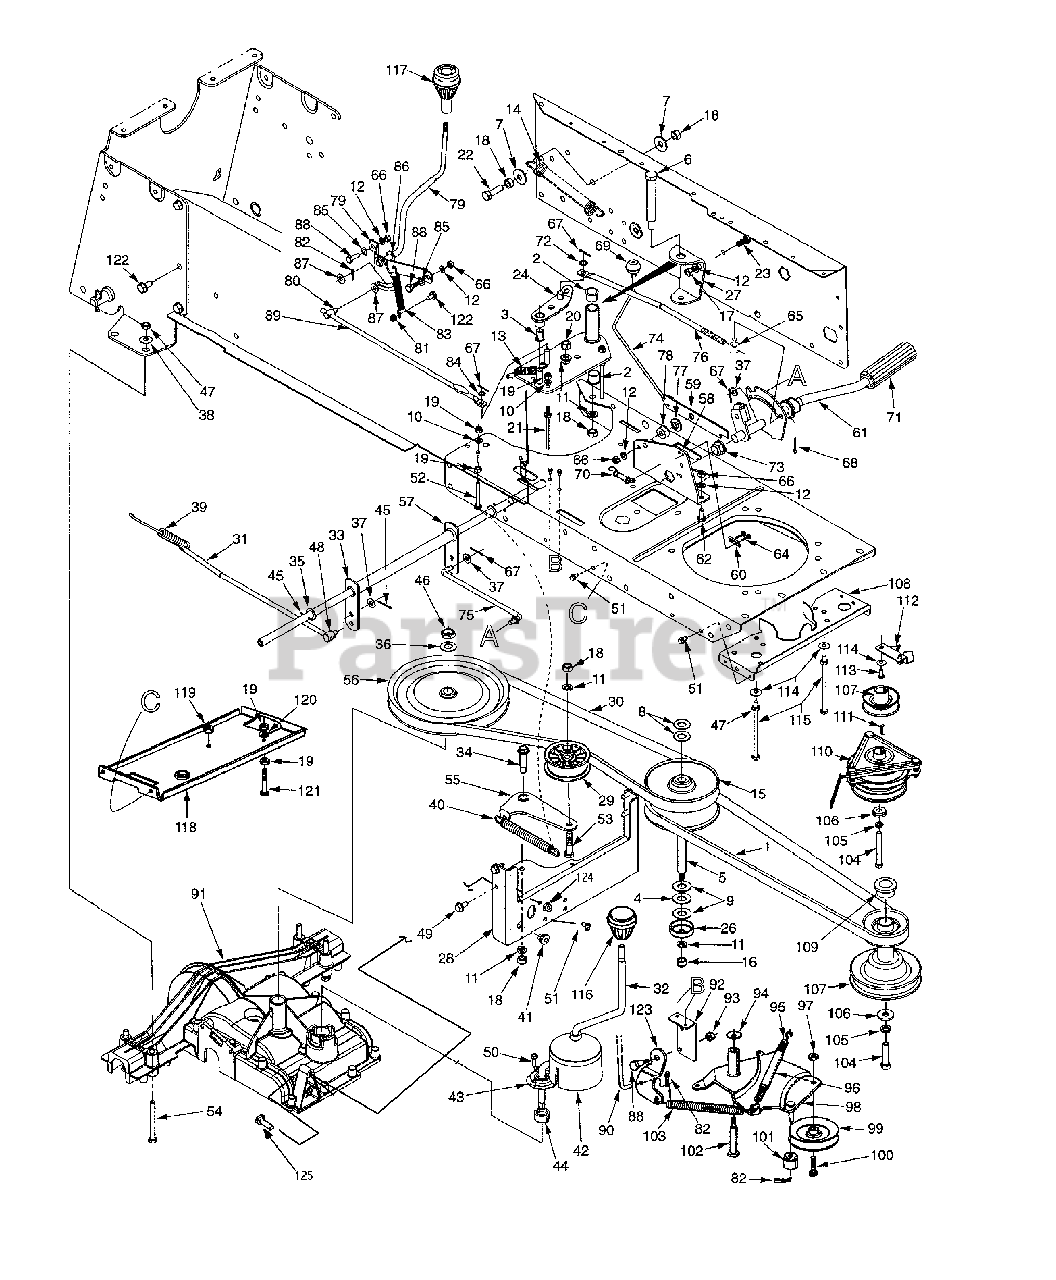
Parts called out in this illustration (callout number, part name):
1	"V"-Belt
2	Flange Brg.
3	Flange Nyliner Brg.
4	Thrust Brg.
5	Shaft
6	Shld. Bolt 3/8-24 Thd.
7	Bell-Wash. .396" I.D. x 1.14" O.D.
8	Fl-Wash. .56" I.D. x 1.12" O.D.
9	Fl-Wash. .5" I.D. x 1" O.D.
10	L-Wash. 1/4" I.D.
11	L-Wash. 3/8" I.D.
12	L-Wash. 5/16" I.D.
13	Ext. Spring 2.54" Lg.
14	Ext. Spring 6.96" Lg.
15	Variable Speed Pulley
16	Hex L-Nut 3/8-24 Thd.
17	Hex Nut 5/16-24 Thd. (Gr. 5)
18	Hex Nut 3/8-16 Thd. (Gr. 5)
19	Hex Nut 1/4-20 Thd. (Gr. 5)
20	Hex Nut 3/8-24 Thd.
21	Belt Keeper
22	Hex Bolt 3/8-16 x 1.25" Lg.
23	Hex Bolt 5/16-24 x .75" Lg. (Gr. 5)
27	Support Brkt.
30	"V"-Belt
31	Brake Rod
32	Shift Lever
33	Flange Nyliner Brg.
34	Shld. Bolt 3/8-16 Thd.
35	Fl-Wash. .5" I.D. x .875" O.D.
36	Bell-Wash. .567" I.D. x 1.125" O.D.
37	Fl-Wash. 5/16" I.D.
38	Bell-Wash. .345" I.D. x .88" O.D.
39	Ext. Spring 7.3" Lg.
40	Ext. Spring 6.12" Lg.
41	Plastic Bushing
42	Boot Shifter
43	Shifter Snout
44	Shifter Insert
45	Cotter Pin 1" Lg.
46	Hex Jam Nut 9/16-18 Thd.
47	Hex Nut 5/16-18 Thd. (Gr. 5)
48	Ferrule
49	Hex Wash. AB-Tap Scr. 5/16-18 Thd.
50	Hex Wash. TT-Tap. Scr. 1/4-20 x .75"
51	Hex Wash. Hd. TT-Tap Scr. 1/4-20 x .5"
52	Hex Bolt 1/4-20 x 2" Lg. (Gr. 5)
53	Hex Bolt 3/8-16 x 1.75" Lg. (Gr. 5)
54	Hex Bolt 5/16-18 x 3" Lg. (Gr. 5)
56	Trans. Pulley
64	Hex Hd. Tap Scr. #10-16 x .75" Lg.
65	Ferrule
66	Hex Nut 5/16-18 Thd.
67	Cotter Pin 1" Lg.
68	Cotter Pin 1/8" Dia. x 1" Lg.
69	Ball Knob
70	Ext. Spring 2.51" Lg.
71	Foot Pad
72	Fl-Wash. 3/8" I.D. x .62" O.D.
73	Hex Flange Bearing
74	Pedal Lock Rod
75	Brake Link Rod
76	Speed Control Link
77	Shld. Spacer
78	Spacer .34" I.D. x .87" O.D.
79	Speed Selector Lever Ass'y.
80	Ferrule
81	Hex L-Nut 5/16-18 Thd.
82	Hairpin Clip
83	Ext. Spring 3.97" Lg.
84	Fl-Wash. 3/8" I.D. x .62" O.D.
85	Spr. Wash. 7/16" I.D.
86	Fl-Wash. .531" I.D. x .93" O.D.
87	Fl-Wash. 3/8" I.D. x .87" O.D.
88	Shld. Bolt .437" x .286"
89	Speed Control Link Rod
90	Deck Control Rod
91	Transmission Complete
92	Parking Brake Mtg. Brkt.
93	Hex L-Nut 5/16-18 Thd.
94	Bell-Wash. .38" I.D. x .88" O.D.
95	Extension Spring 6.37" Lg.
96	Conduit 4" Lg.
97	Hex Cent. L-Nut 3/8-24 Thd.
98	Idler Brkt. Deck Ass'y.
99	"V"-Belt Idler
100	Hex Bolt 3/8-24 x 1.5" Lg.
101	Spacer
102	Shld. Bolt .498" Dia. x 2.05"
103	Extension Spring 6.12" Lg.
104	Hex Bolt 7/16-20 x 2.75" Lg.
105	L-Wash. 7/16" I.D.
106	Fl-Wash. .44" I.D. x 1.25" Lg.
107	Engine Pulley
110	Electric PTO
111	Sq. Key 1/4" x 1" Lg.
114	Bell-Wash. .345" I.D. x .88" O.D.
115	Hex Bolt 5/16-18 x 5.25" Lg.
116	Knob
117	Shift Knob
119	Hex Cent. L-Nut 3/8-16 Thd.
120	L-Wash. 1/4" I.D.
121	Hex Bolt 1/4-20 x 2" Lg.
122	Hex AB-Tap Scr. 5/16 x .75" Lg.
123	Deck Control Pivot Brkt.
124	Hex L-Nut 5/16-18 Thd.
125	Hex Bolt 5/16-18 x 1.375" Lg.
